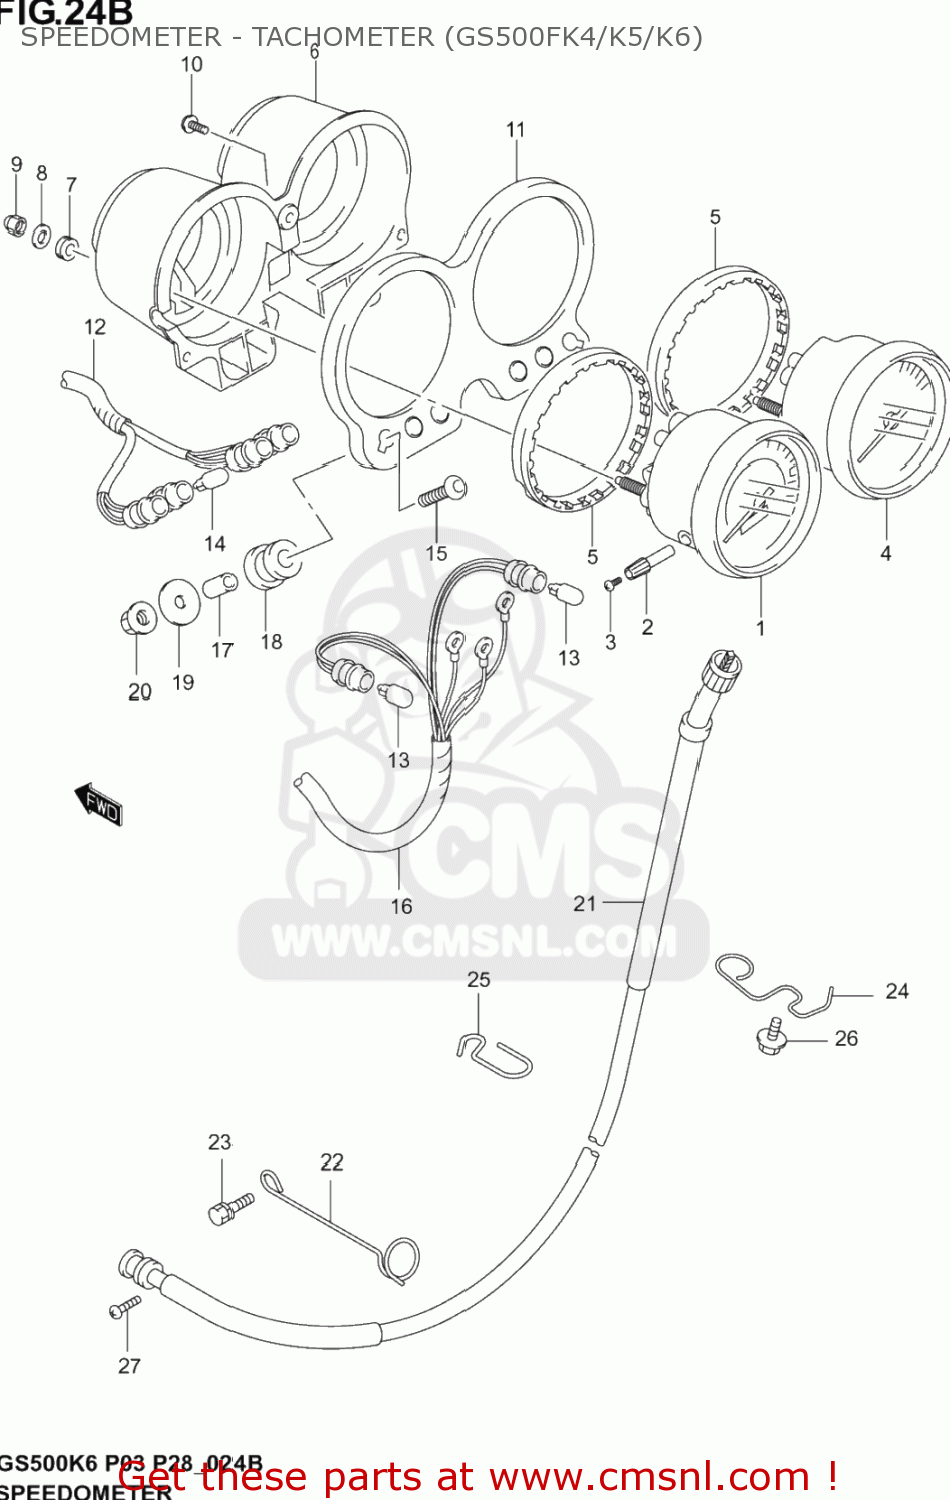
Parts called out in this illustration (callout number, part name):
1	SPEEDOMETER
2	KNOB
3	ROTOR,SPEED
4	TACHOMETER
5	DAMPER
6	COVER
7	CUSHION
8	WASHER
9	NUT
10	SCREW
11	BRACKET METER
12	SOCK.&CORD,PIL
13	BULB(12V1.7W,T10)
14	BULB (12V, 1.7W, T6.5)
15	BOLT(6X30)
16	SOCK.&CORD PIL
17	SPACER(6.4X9X17)
18	CUSHION,METER BRACKET
19	WASHER(6.5X28X1.6)
20	NUT
21	CABLE ASSY,SPEEDOMETER
22	GUIDE,CABLE NR
23	BOLT OIL LEVEL
24	GUIDE,CABLE NR
25	GUIDE,CABLE NR
26	SCREW
